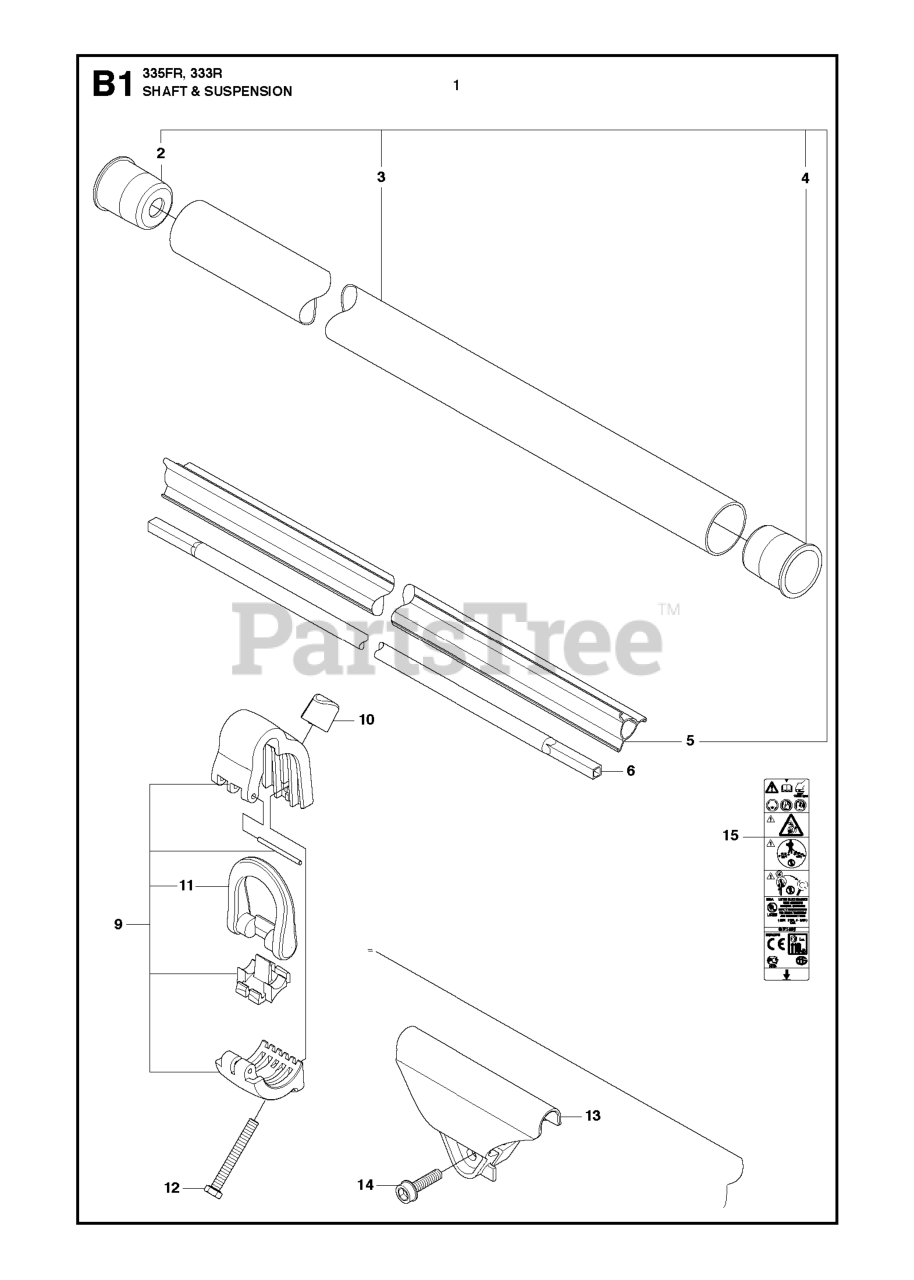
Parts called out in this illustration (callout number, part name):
1	TUBE
2	PLUG
3	TUBE
5	GUIDE
6	SHAFT
9	SUPPORT LOOP
12	SCREW M6S 5X40
13	CABLE HOLDER
15	RP WARNING DECAL
